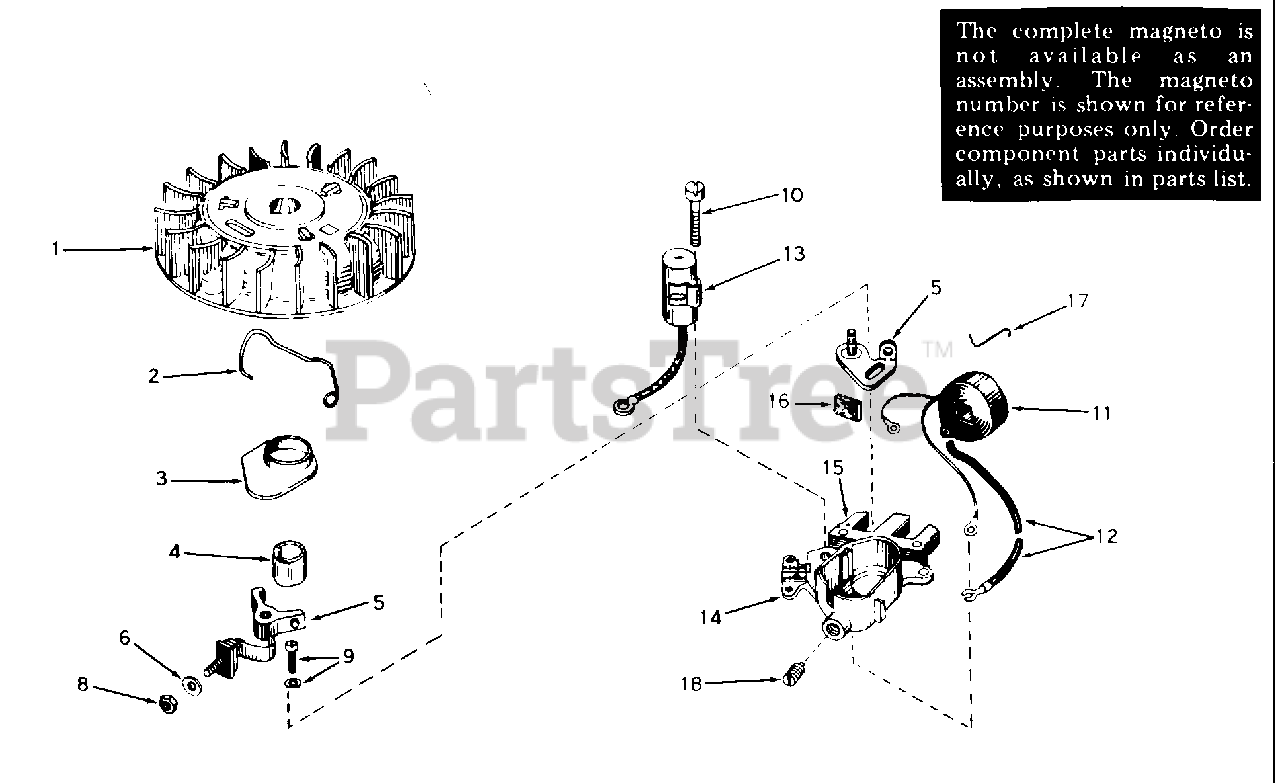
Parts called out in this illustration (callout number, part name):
1	Flywheel
2	Spring, Breaker box cover
3	Cover, Breaker box
4	Cam, Breaker
5	Breaker Points (also available in Pac kaged Part #740037B)
6	Washer, Terminal
8	Nut, Terminal
9	Screw & Lockwasher
10	Screw, Condenser
11	Coil Assy. (Incl. 12)
12	Wire, Lead
13	Condenser
14	Core & Plate
15	Stator Assy. Incl. 2,5 thru 14,16,17, 18
16	Felt, Cam wiper
17	Clip, Coil locking
18	Screw Assy., Friction
